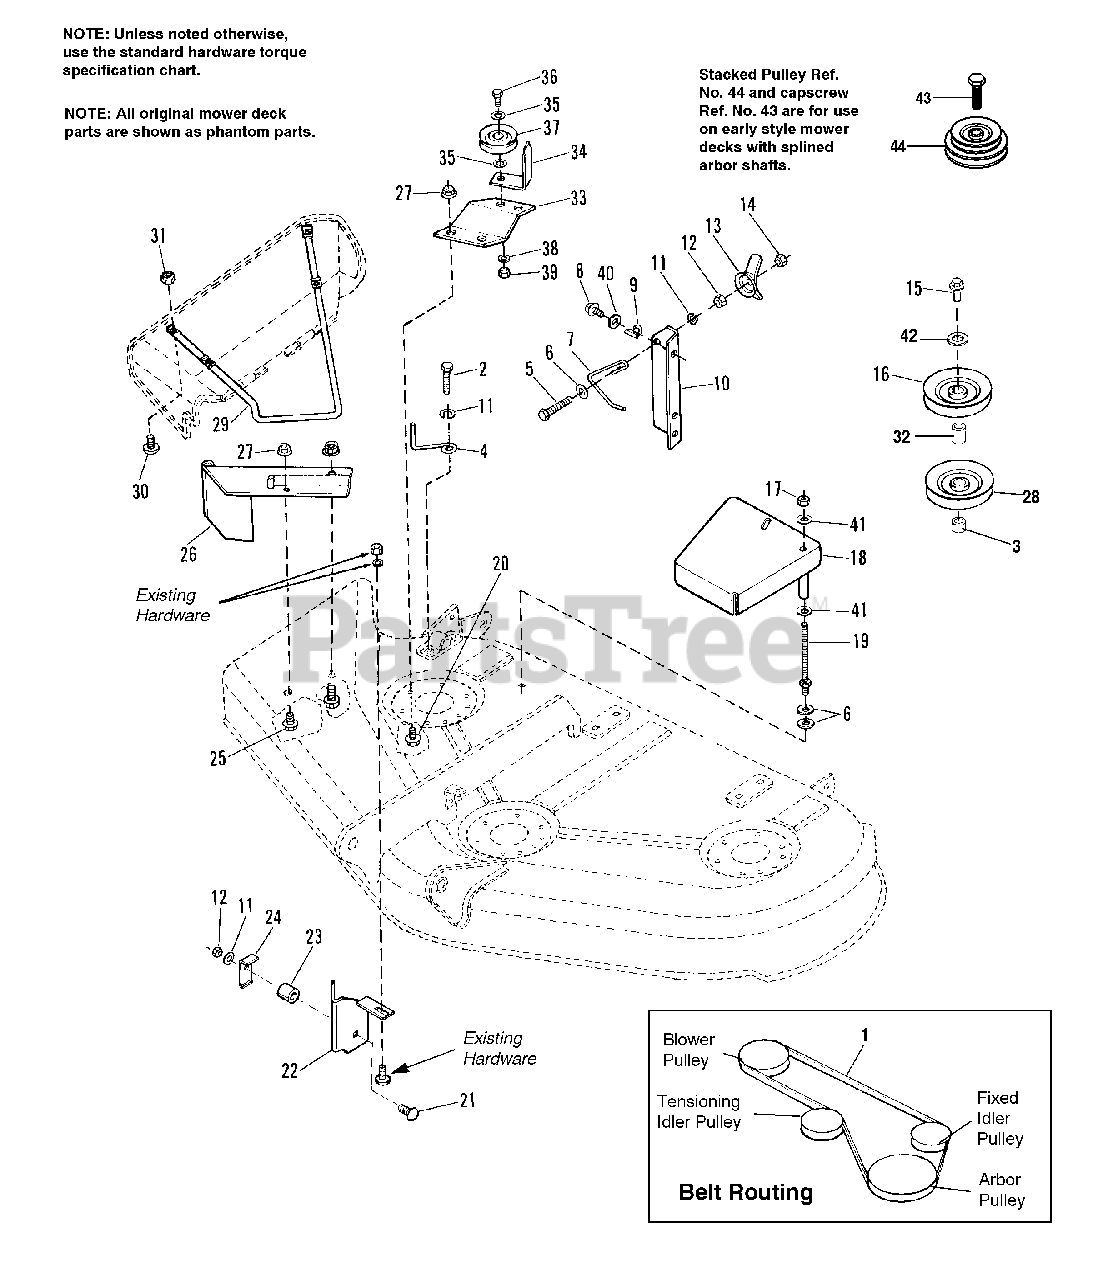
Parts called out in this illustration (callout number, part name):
1	Belt - 50"
2	CAPSCREW 5/16-18 x 1-1/2
3	HUB
5	CAPSCREW 5/16-18 x 2-1/2
6	WASHER, Flat
7	SPRING LATCH
8	SCREW, Taptite 1/4-20 x 1/2
10	ANCHOR, Turbo
11	LOCKWASHER 5/16
12	NUT, Hex, 5/16-18
13	NUT, Wing Assy, 5/16
14	NUT, Hex, Centerlock 5/16-18
15	NUT, Sleeve
16	PULLEY ASSY Turbo
17	HEX NUT, Nylock
18	SHIELD ASSY., Belt
19	STUD, 5/16-18 x 5-13/64
20	CAPSCREW, Hex Hd. 5/16-18 x 7/8
21	CARRIAGE BOLT 5/16-18 x 1-1/4
22	BRACKET, Cutoff
24	BRACKET, "L"
25	CARRIAGE BOLT, 5/16-18 x 3/4
26	PIVOT ASSY., 50
27	NUT, Hex, Flange
28	V-PULLEY
29	ROD, Deflector
30	SCREW, Truss Hd
31	NUT, Nylock, #10-24
32	HUB, Pulley, Double
33	BRACKET, Idler, Turbo
34	LATCH, Belt Cover
35	WASHER, Flat
36	CAPSCREW, 3/8-16 x 1-1/2
37	PULLEY ASSY, Idler
38	LOCKWASHER, 3/8
39	NUT, Hex, 3/8-16
40	WASHER, Flat, 1/4
41	WASHER, Flat
42	WASHER, Belleville
43	CAPSCREW, 7/16-14 x 2
44	PULLEY, Double
